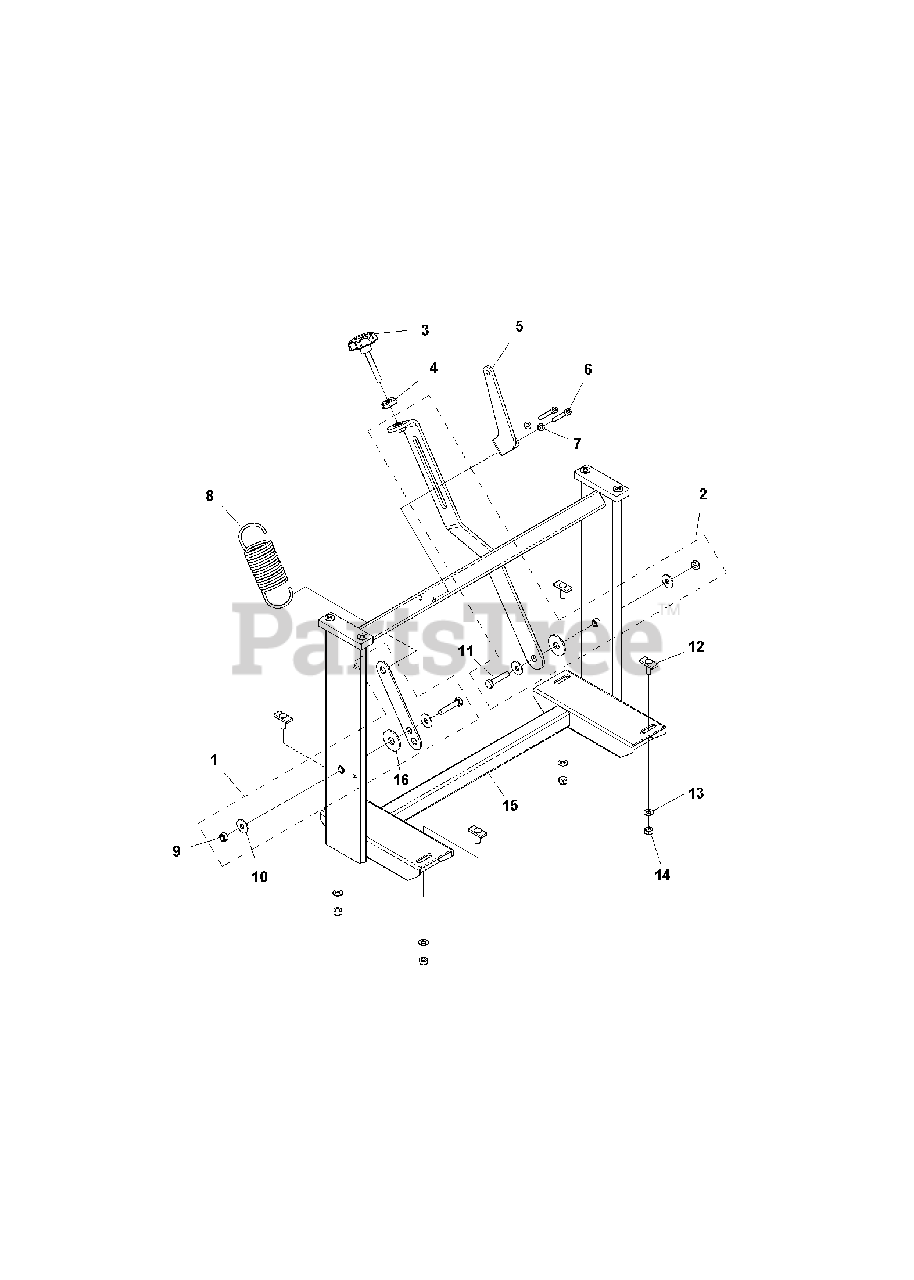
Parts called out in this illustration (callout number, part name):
9	HEXAGON LOCKING NUT
13	WASHER
14	HEXAGON LOCKING NUT
